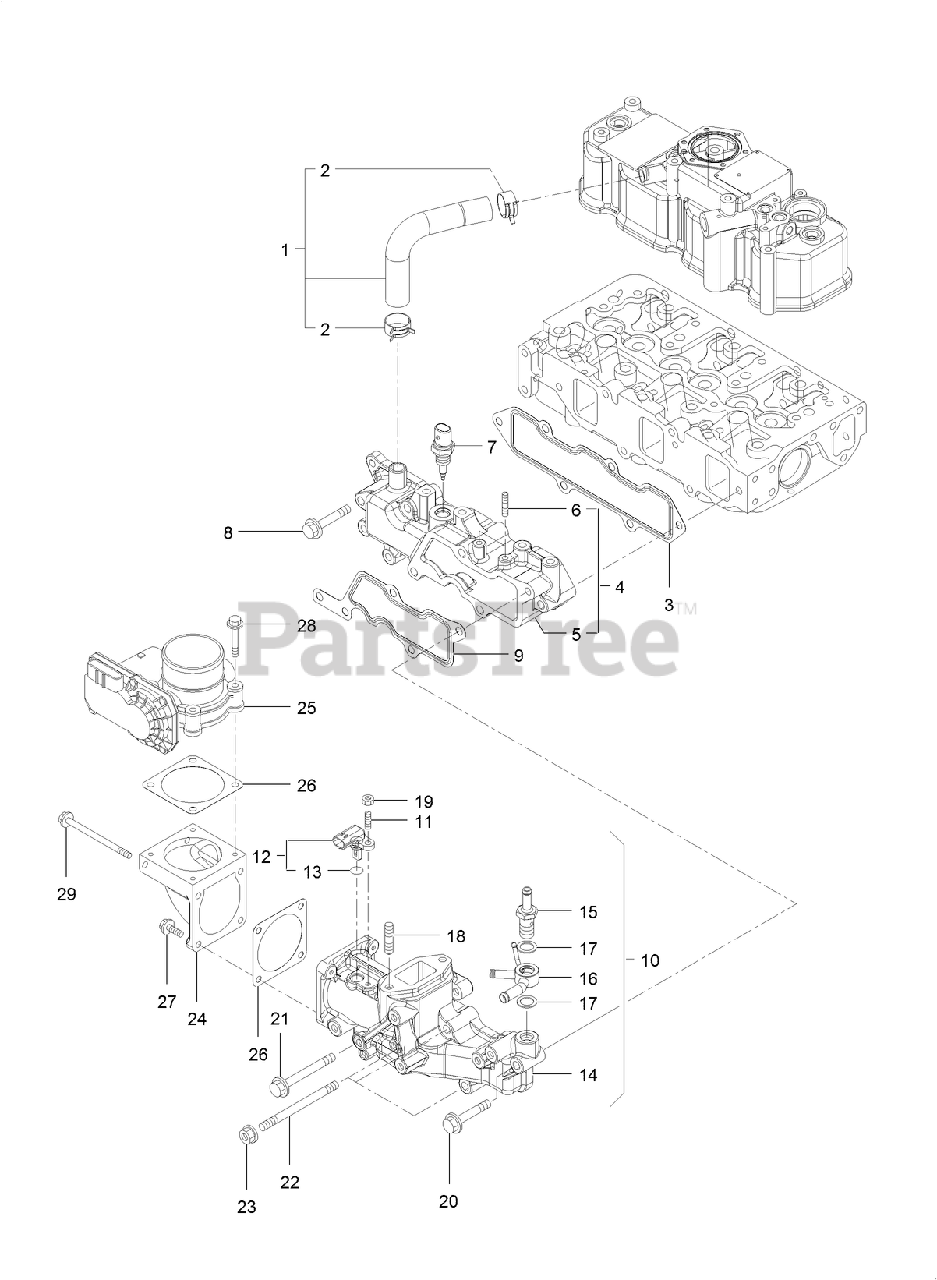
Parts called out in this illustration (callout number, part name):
2	CLIP-HOSE
3	GASKET-MANIFOLD, INTAKE
4	INTAKE MANIFOLD ASM
5	MANIFOLD-INTAKE
7	SENSOR-TEMP, AIR
9	GASKET-COLLECTOR
10	INTAKE COLLECTOR ASM
12	SENSOR-TEMP, AIR
13	O-RING
14	COLLECTOR-INTAKE
15	JOINT-HOSE
16	JOINT-HOSE
17	WASHER-SEAL
24	BEND-INLET
25	BODY-THROTTLE
26	GASKET-THROTTLE
